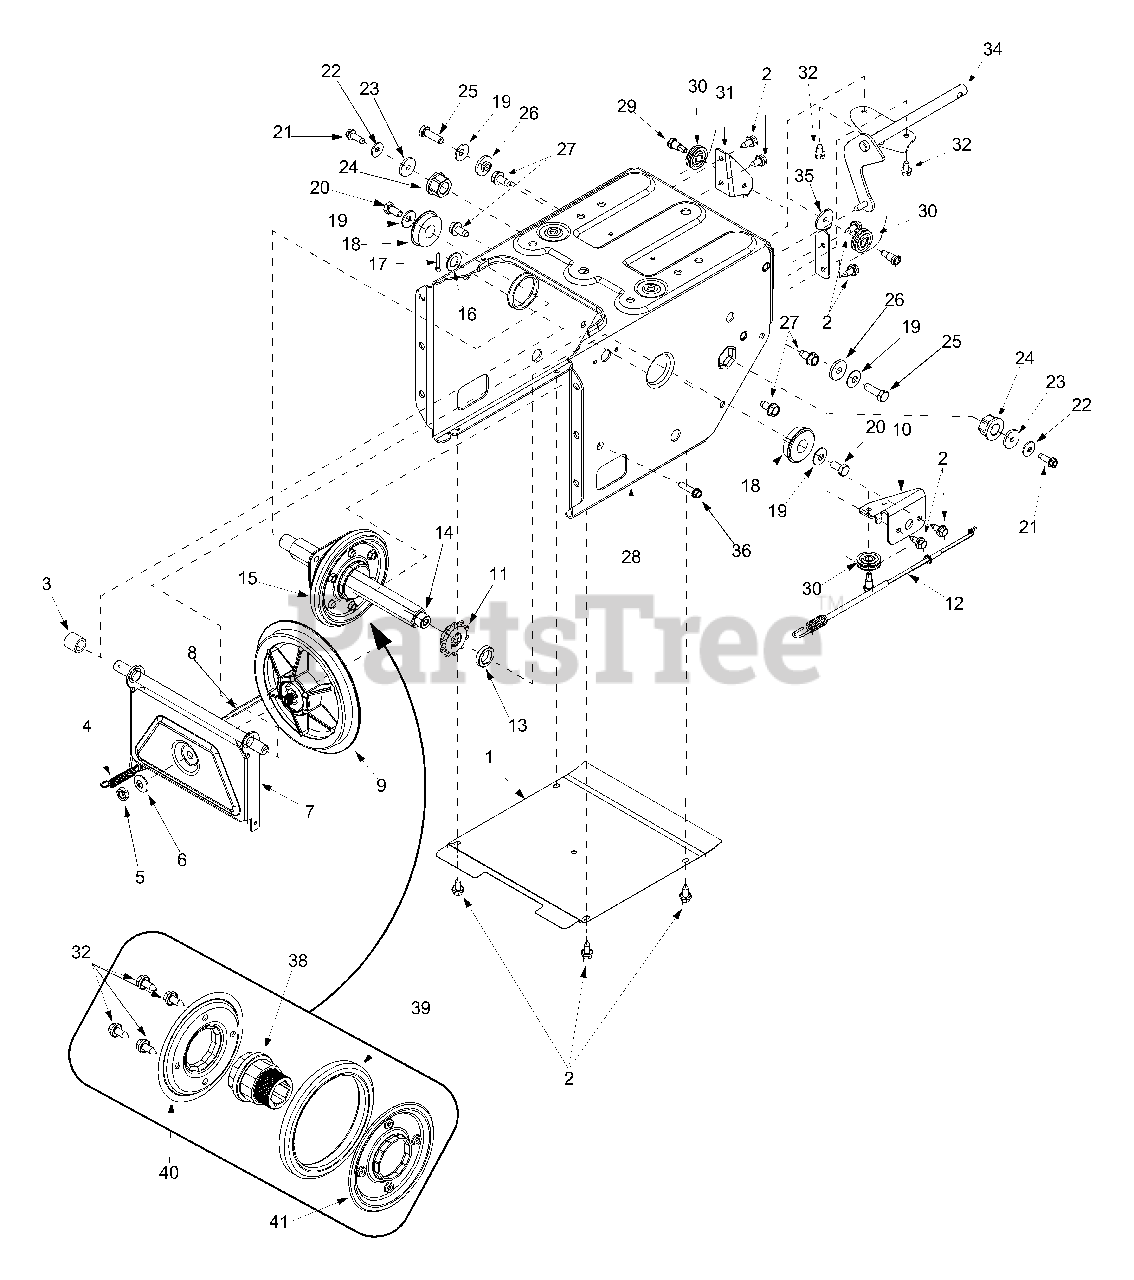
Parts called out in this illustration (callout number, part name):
3	Spacer .508 ID x .75 OD
4	Extension Spring
5	Jam Nut 3/8-24
6	Bell Washer .401 ID x .87 OD
9	Friction Disc
12	Auger Cable 44.75"
13	Spacer .675 ID x 1" OD
14	Hex Track Shaft
15	Friction Wheel Assembly
16	Flat Washer .536 ID x .93 OD
17	Cotter Pin
18	Ball Bearing
19	Bell Washer .34 ID x .872 OD
20	Hex Cap Screw 5/16-18 x .625
21	Tap Screw 1/4-20 x .75
22	Bell Washer .265 ID x .75 OD
23	Flat Washer 1/4 ID x .93 OD
24	Hex Flange Bearing
25	Hex Cap Screw 5/16-18 x 1"
26	Shoulder Spacer
27	Tap Screw 5/16-18 x .625
29	Hex Screw 1/4-28 x .375
30	Cable Roller
37	Friction Wheel Bearing
38	Friction Wheel Hub
39	Friction Wheel Rubber
40	Friction Plate
41	Friction Plate
